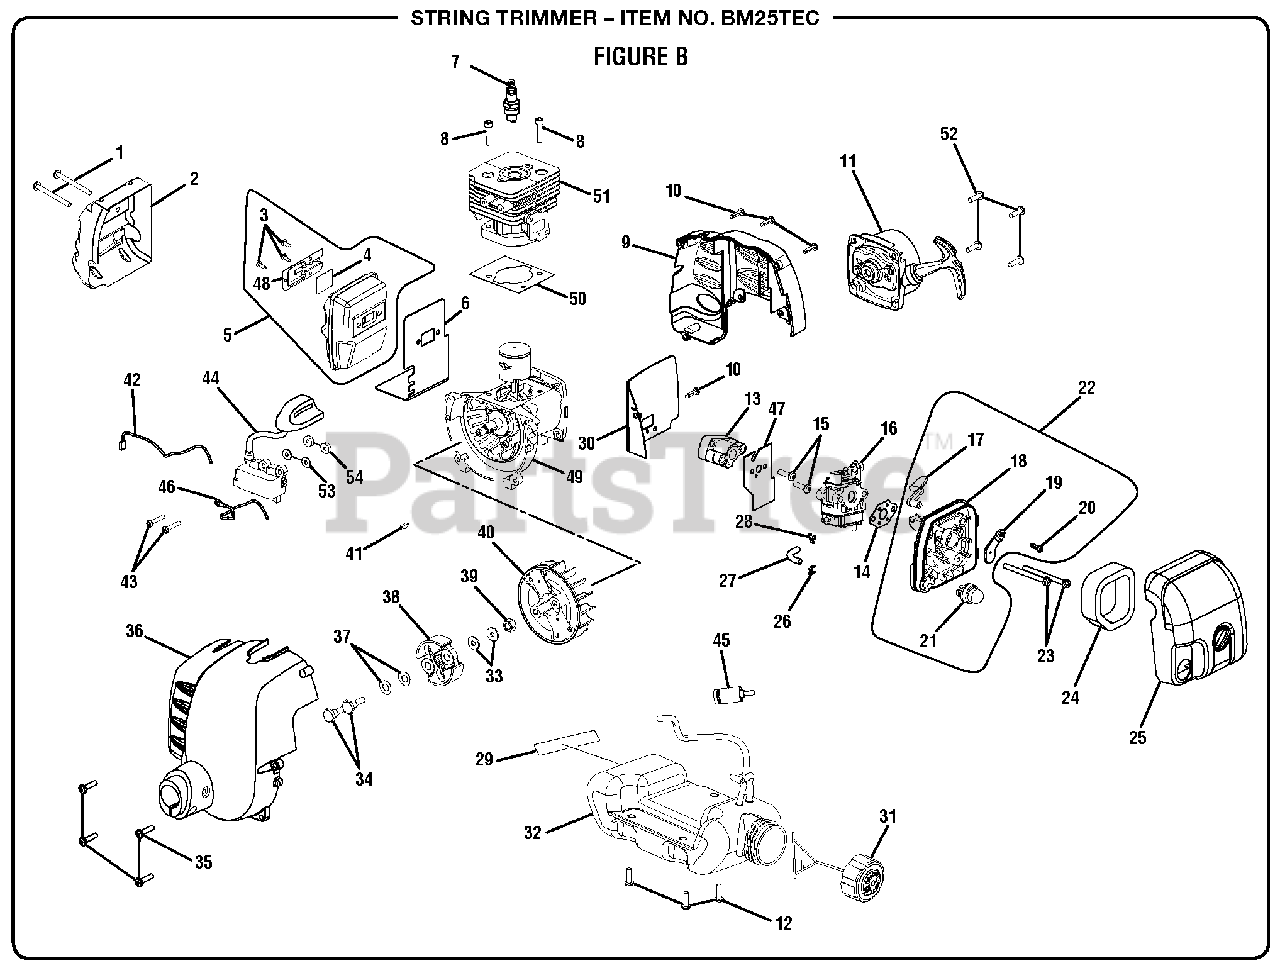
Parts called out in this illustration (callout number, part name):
1	Screw (M5 x 50 mm, Torx Slotted Recessed Pan Hd.)
2	Heat Shield
3	Screw (6-20 x 1/4 in., T20 Torx Pan Hd. S.T.)
4	Screen
5	Muffler Assembly
6	Muffler Gasket
7	Spark Plug (RCJ4Y)
8	Screw (M5 x 22 mm, Soc. Hd.)
9	Engine Housing, Rear
10	Screw (M4 x 16 mm, Torx Recessed Pan Hd.)
11	Starter Recoil Assembly
12	Screw (M5 x 16 mm, Torx Slotted)
13	Heat Dam Insulator
14	Carburetor Gasket
15	Screw (M5 x 31 mm Torx Slotted Recessed Pan Hd.)
16	Carburetor Assembly
17	Choke Lever
18	Carburetor Plate
19	Choke Plate
20	Screw (M4 x 12 mm, Slotted Recessed Pan Hd.)
21	Primer Assembly
22	Filter Housing Assembly
23	Screw (M5 x 60 mm, Slotted Recessed Pan Hd. Machine)
24	Element
25	Air Box Cover Assembly
26	Hose Clip
27	Fuel Line (45 mm)
28	Hose Clip
29	Combustion Warning Label
30	Insulator Gasket
31	Fuel Cap Assembly
32	Fuel Tank and Cap Assembly
33	Washer
34	Clutch Screw
35	Screw (M5 x 20 mm Torx Slotted Recessed Pan Hd.)
36	Front Housing Assembly
37	Curved Washer
38	Clutch Assembly
39	Rotor Nut
41	Woodruff Key (10 mm x 3 mm)
42	Lead Wire, Black
43	Screw (M4 x 22 mm, T20 Torx Slotted Recessed Pan Hd.)
44	Coil Boot Assembly
45	Fuel Filter
46	Lead Wire, Red
48	Trimmer Outlet
49	Crankcase Assembly
52	Screw (M5 x 16 mm)
53	Washer (ID4.2 x OD10 x 1t)
54	Phenolic Spacer (Ignition Module)
